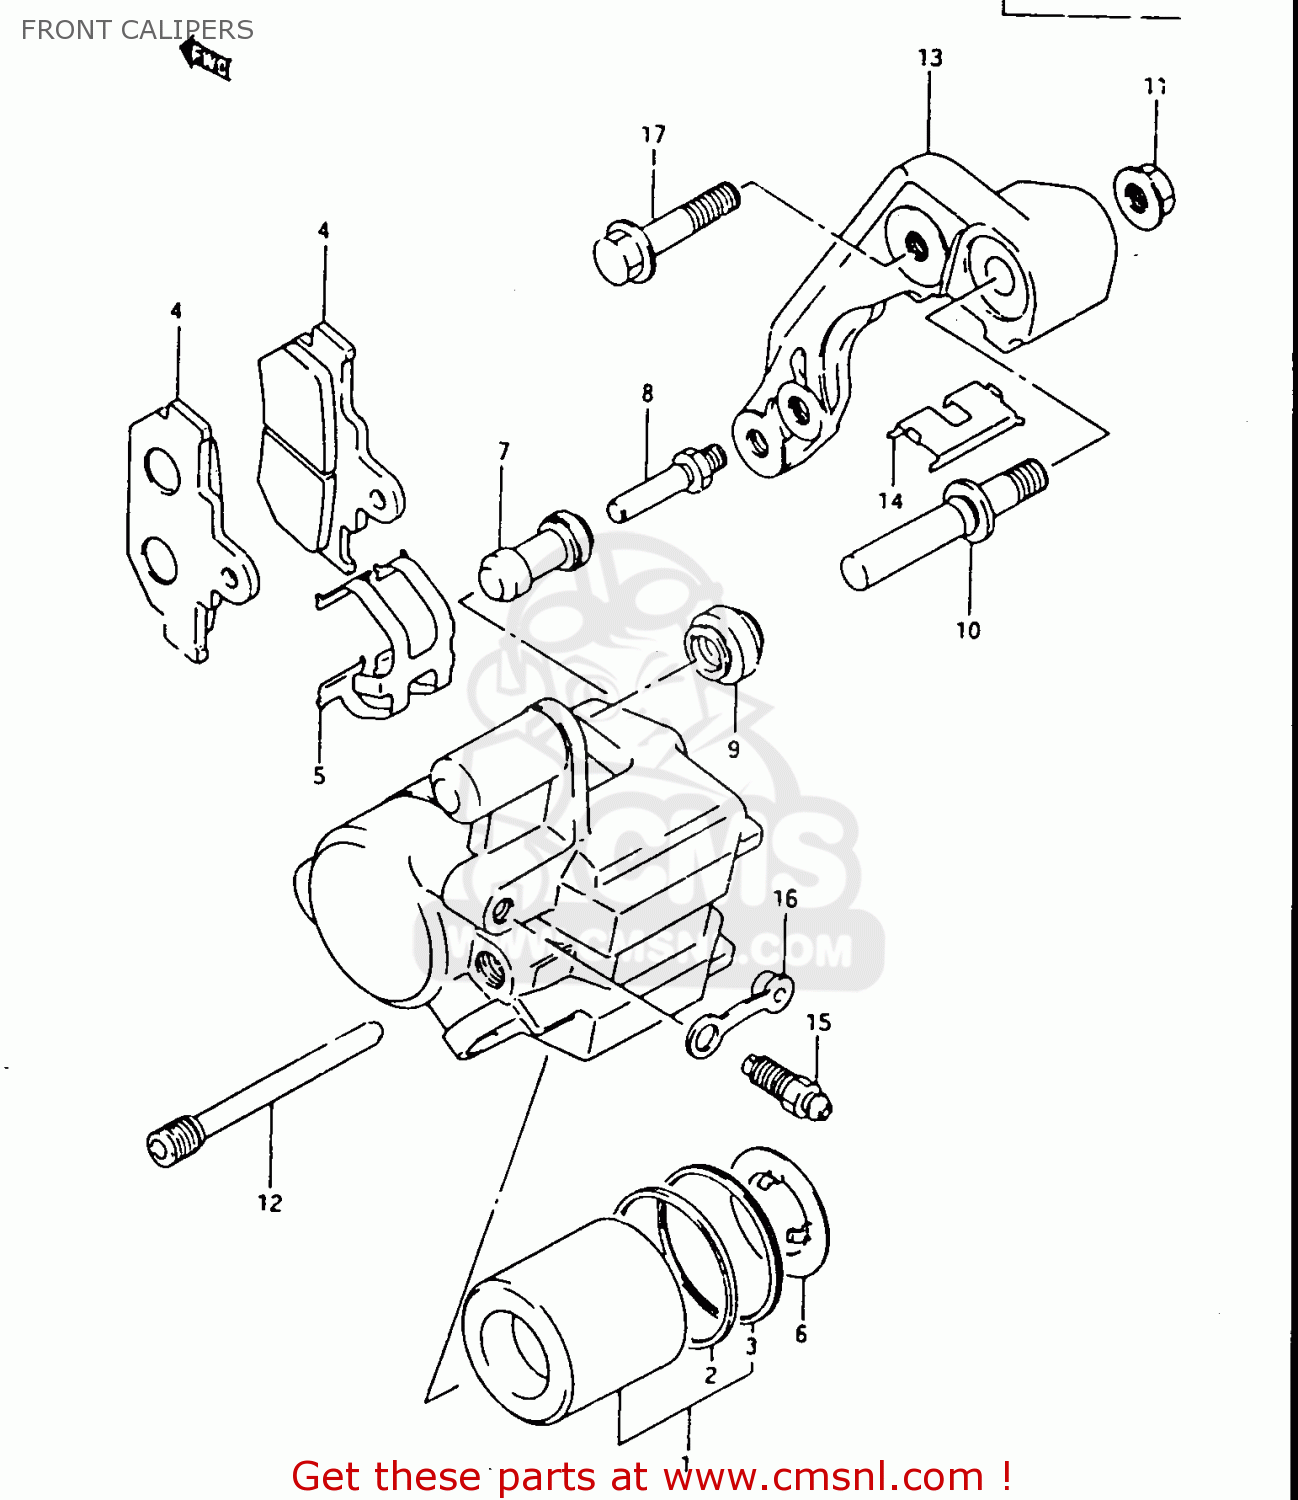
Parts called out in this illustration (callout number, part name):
1	PISTON SET,CALIPERS
2	SEAL,PISTON
3	DUST SEAL,PISTON
4	PAD
5	SPRING,PAD
6	SHIM
7	BOOT
8	PIN,BOLT
9	BOOT
10	PIN,SLIDE
11	NUT,SLIDE PIN
12	PIN,HANGER
13	BRACKET
14	RETAINER
15	BLEEDER
16	CAP,BLEEDER
17	BOLT(8X35)
